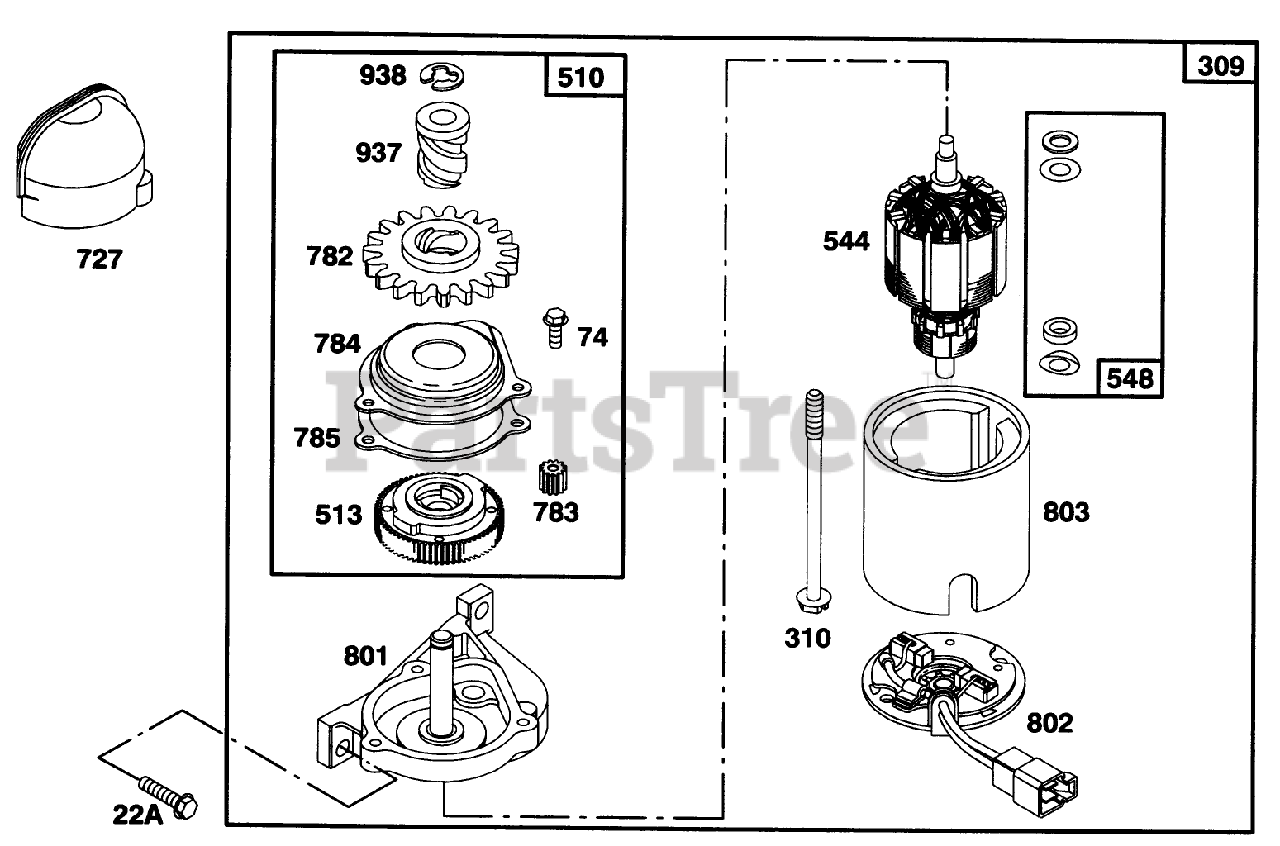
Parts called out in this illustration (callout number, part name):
22A	SCREW - CARBUERTOR MTG
74	SCREW - SEM
510	DRIVE SET
513	CLUTCH - STARTER
548	WASHER ASSEMBLY
727	COVER - STARTER
782	GEAR - STARTER
938	RETAINER - LOCK
